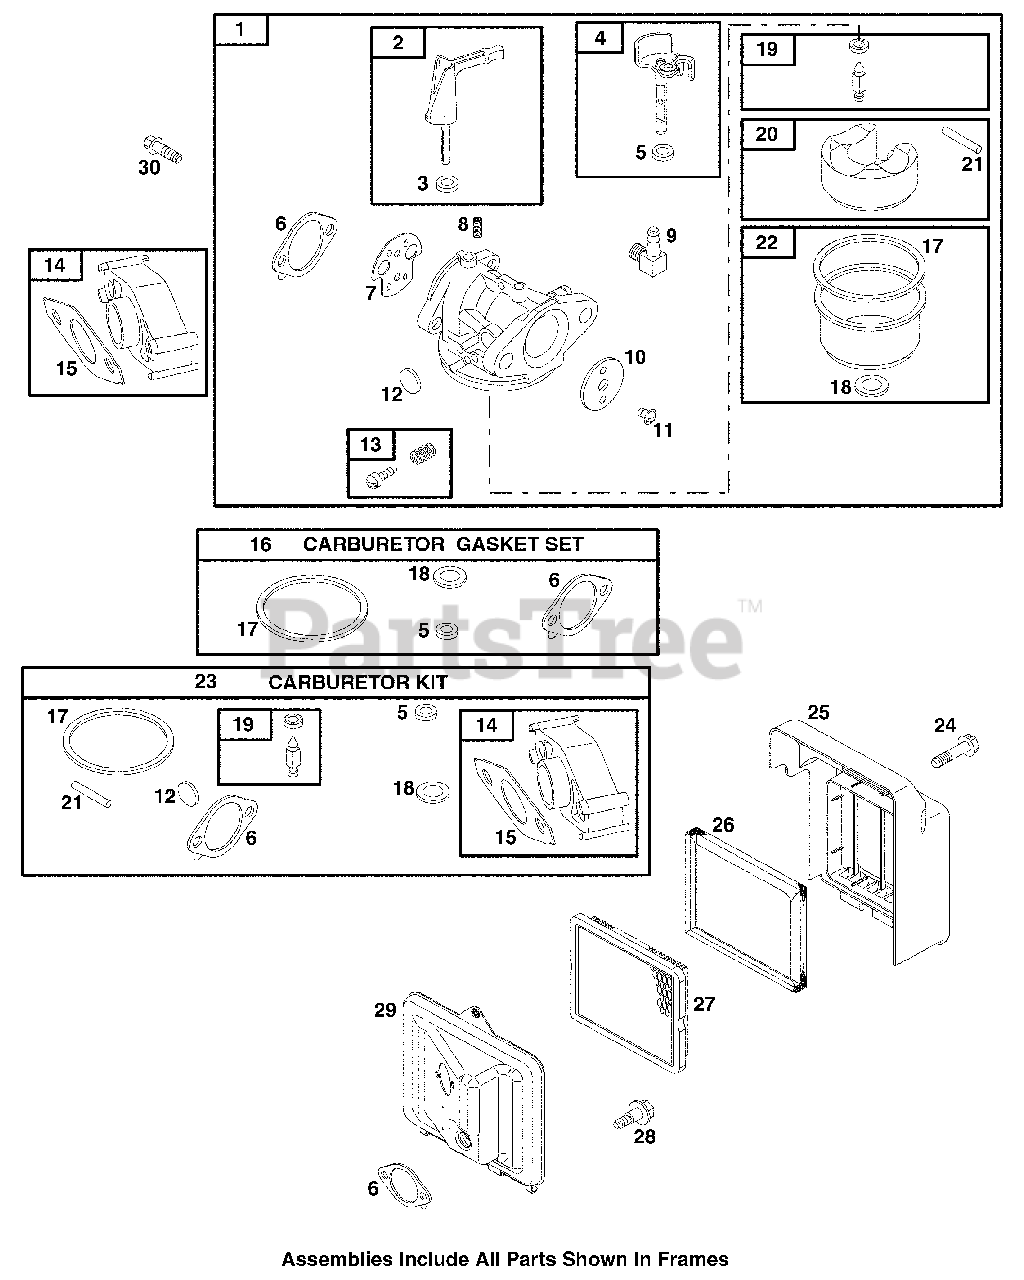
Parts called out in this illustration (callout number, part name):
1	Carburetor
2	Choke Shaft
3	Washer
4	Throttle Shaft
5	Washer
6	Air Cleaner Gasket
7	Choke Valve
8	Spring-Detent (Choke)
9	Hose Connector
10	Throttle Valve
11	Screw
12	Welch Plug
13	Idle Speed Kit
14	Carburetor Spacer
15	Intake Gasket
16	Carburetor Gasket Set
17	Float Bowl Gasket
18	Sealing Washer
19	Needle Valve
20	Carburetor Float
21	Float Hinge Pin
22	Bowl-Float
23	Carburetor Kit
24	Screw
25	Cover-Air Cleaner
26	Pre-Cleaner Filter
27	Air Cleaner Cartridge Filter
28	Screw
29	Air Cleaner Base
30	Screw
